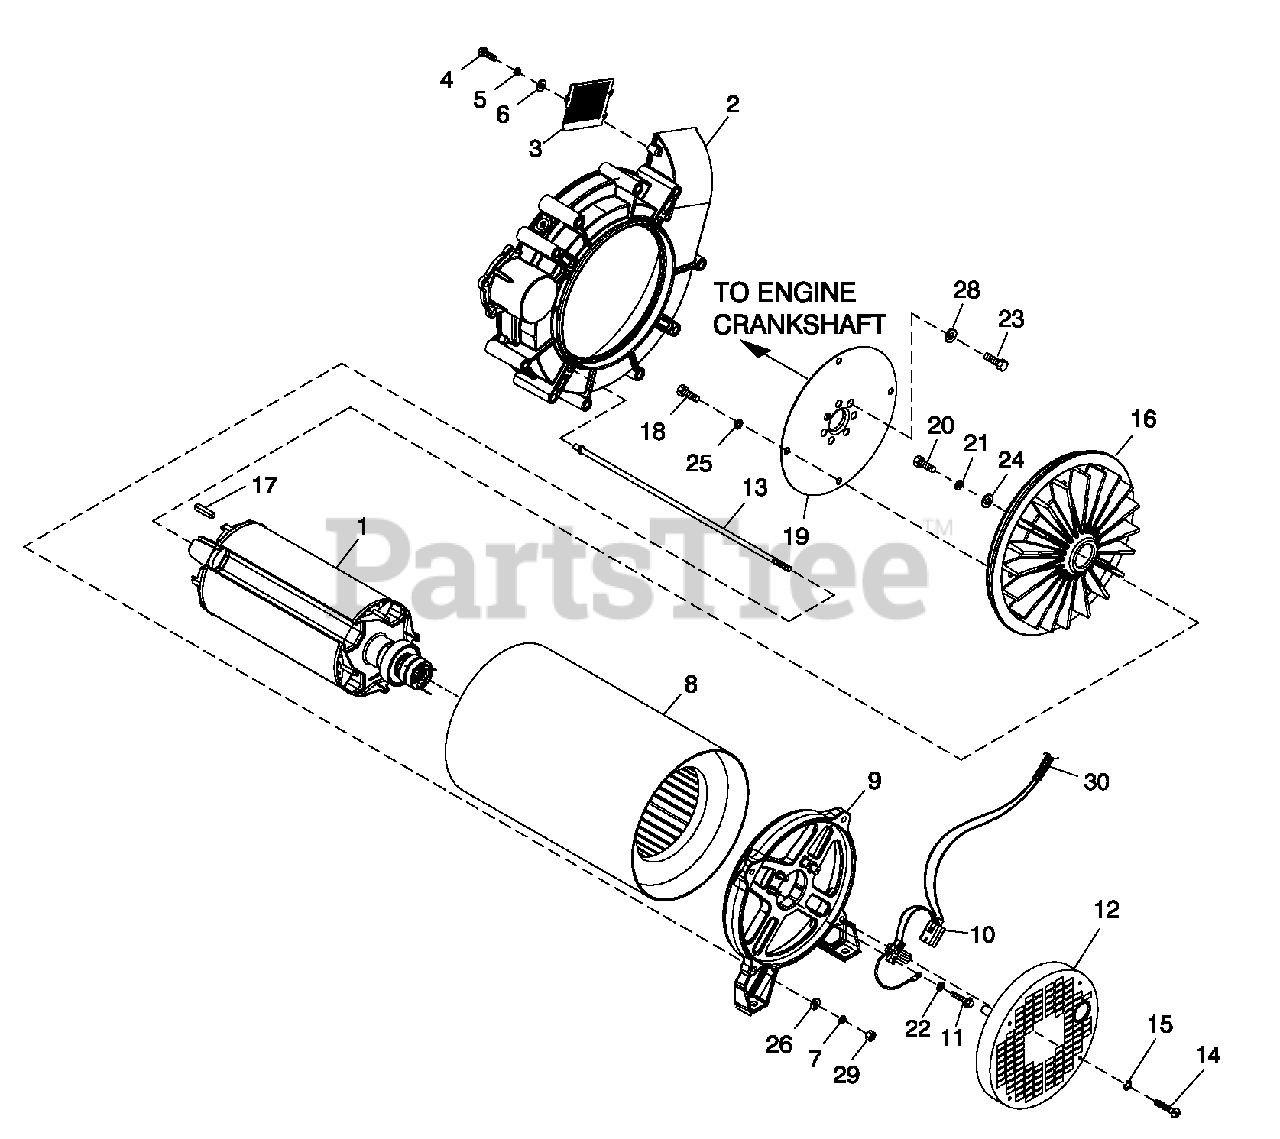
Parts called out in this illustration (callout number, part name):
1	RTR-104-22AD1 HI EFF
2	HOUSING BLOWER MACHINED 2.4L
3	BLOWER HOUSING SCREEN
4	SCREW PPHM M5-0.8 X 8 ZINC
5	WASHER LOCK M5
6	WASHER FLAT M5
7	WASHER LOCK M8-5/16
8	STR-104-22AD1 HI EFF
9	BEARING CARRIER REAR LG PILOT
10	ASSY HOLDER BRUSH
11	SCREW HHC M4-0.7 X 16 G8.8
12	COVER REAR BEARING
13	STUD M8-1.25 475 LONG (27KW)
14	SCREW RHM #10-24 X 2
15	WASHER LOCK #10
16	FLYWHEEL & RINGGEAR ASSY 2.4L
17	KEY SQ 3/8 X 1 STEEL
18	SCREW HHC M10-1.5 X 20 C8.8
19	PLATE FLEX 2.4L 10" ALT
20	SCREW HHC M12-1.75 X 35 G8.8
21	WASHER LOCK M12
22	WASHER SHAKEPROOF INT #8
23	SCREW HHC M12-1.25 X 15 C10.9
24	SPACER ROTOR SHAFT
25	WASHER LOCK M10 RIBBED ZINC
26	WASHER FLAT .34 ID X .75 OD
28	WASHER FLAT .531ID X 1.062OD
29	NUT HEX M8-1.25 G8 CLEAR ZINC
30	CONDUIT FLEX .38"ID ( 18" LG)
